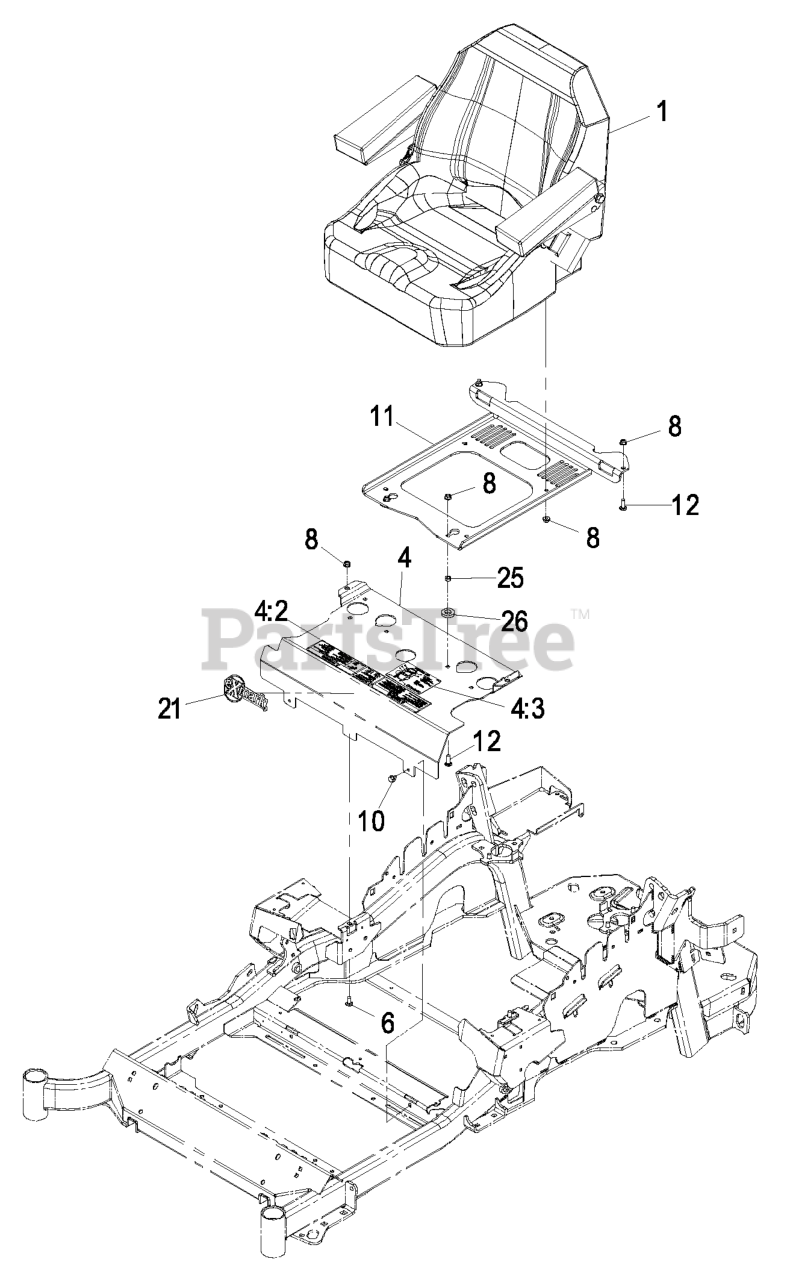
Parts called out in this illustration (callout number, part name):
3	ISOLATOR-SEAT
4	MOUNT-SEAT
4:2	DECAL-CONSOLE
4:3	DECAL-SERVICE AID
6	SCREW-CARR
8	NUT-HF, NI
9	NUT-HF, NI
13	PLATE-SUPPORT, SEAT TILT
14	PLATE-FRAME, SEAT TILT
15	PLATE-LATCH, SEAT
16	BOLT-CARR
17	SPRING-COMPRESSION
18	SCREW-SHOULDER
20	ROD-PROP
24	WASHER-PLAIN
